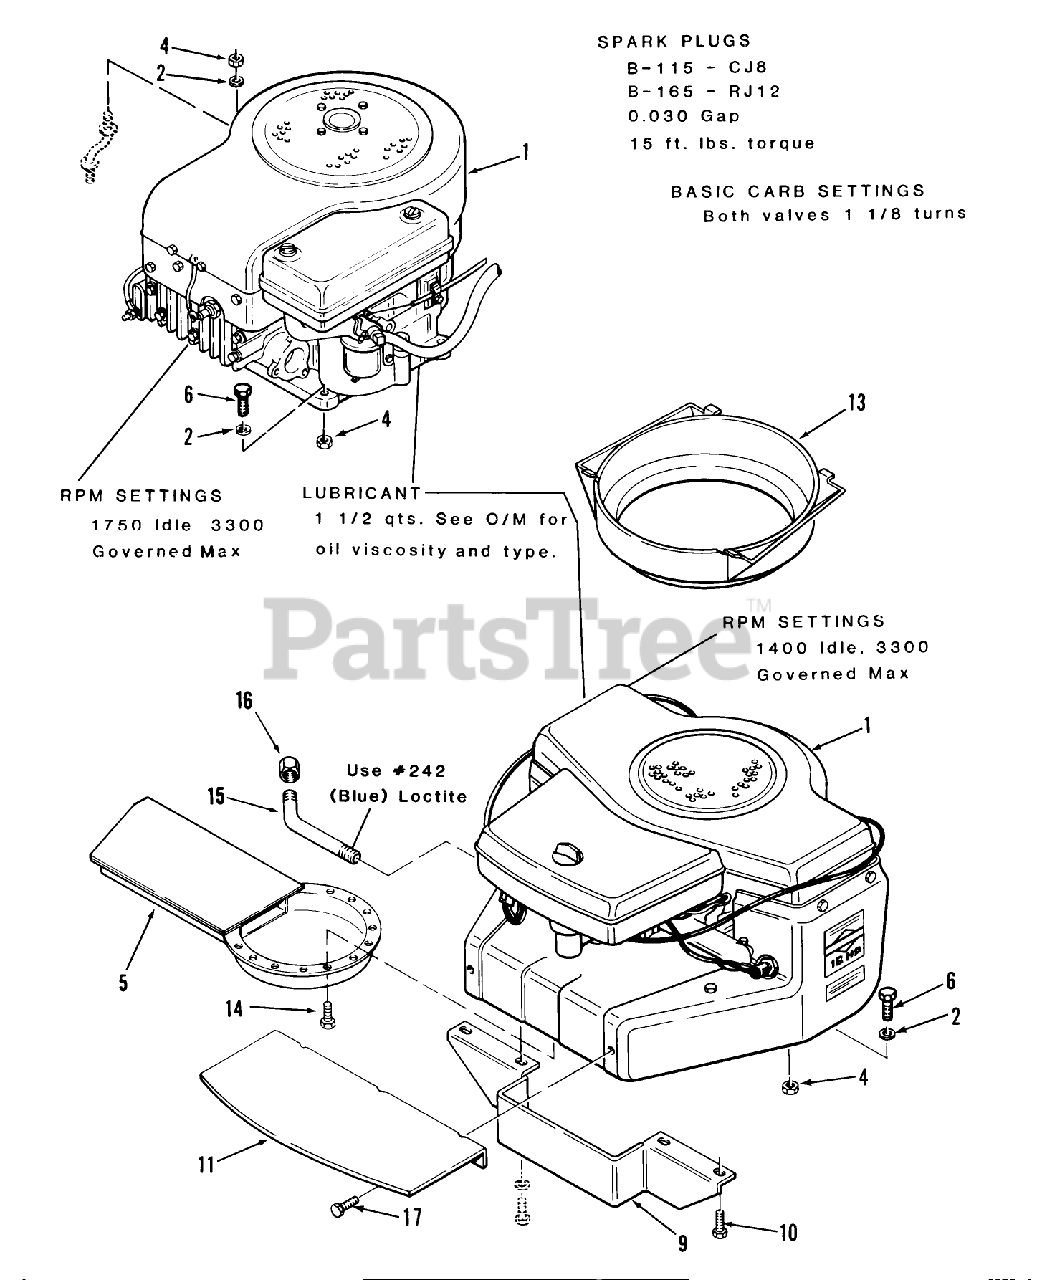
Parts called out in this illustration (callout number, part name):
1	Engine-16HP-BS Model 402707, Type 0130-05 216-5 Only
1	Engine-11HP-BS Model 253707, Type 0131-01-B-115 Only
2	WASHER 5/16 SAE
13	DUCT-AIR INTAKE
